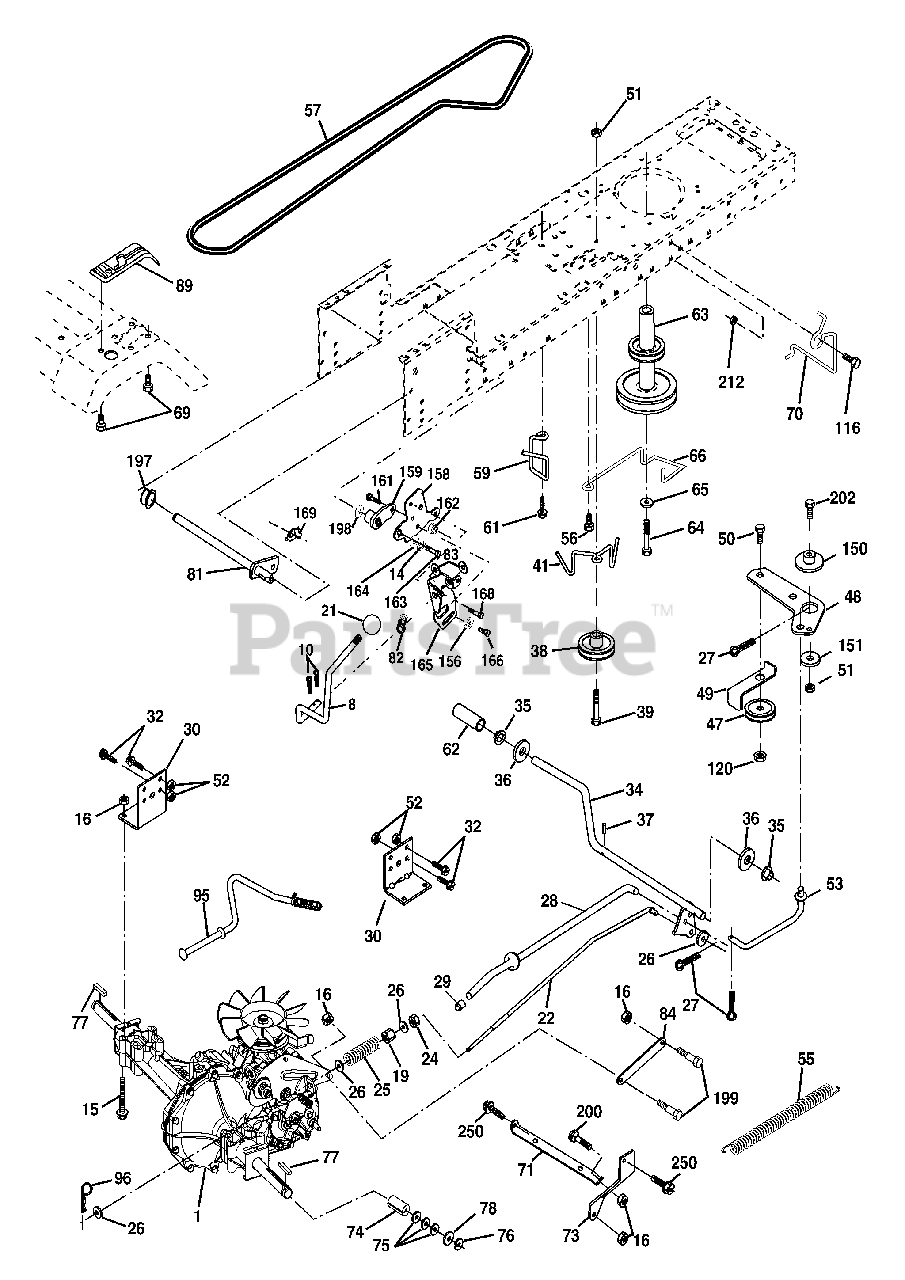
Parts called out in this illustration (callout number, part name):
10	Pin, Cotter 1/8 x 1
14	Washer Lock 1/4
15	Bolt Hex Flghd 5/16-18 Gr. 5
16	Nut, Lock Hex w/Ins 5/16-18 Unc
19	Nut, Lock Hex w/Wsh 3/8-16 Unc
21	Knob
22	Rod, Brake
24	Nut
25	Spring, Rod, Brake
26	Washer 13/32 x 13/16 x 16 Ga.
27	Pin, Cotter 1/8 x 3/4
28	Rod, Parking Brake
29	Cap, Parking Brake
30	Bracket, Transmission
32	Bolt Hex 5/16-18 Unc x 3/4
34	Shaft, Foot Pedal
35	Bearing, Nylon
36	Washer
37	Pin, Roll
38	Pulley, Idler, Composite
39	Bolt
41	Keeper, Belt, Idler
47	Pulley, Idler, V-Belt
48	Bellcrank Clutch Grnd Drustl
49	Retainer, Belt
50	Bolt 3/8-16 x 1-1/2 Gr. 5
51	Nut
52	Nut Crownlock 5/16-28
53	Link, Clutch
55	Spring, Return, Clutch
56	Screw 3/8-16 x 1-1/4
57	V-Belt, Drive
59	Keeper, Belt, Center
61	Screw, 3/8-16 x .875
62	Cover, Pedal
63	Pulley, Engine
64	Bolt Hex 7/16-20 x 4 x Gr. 5-1.5
65	Washer
66	Keeper, Belt Engine Hydro
69	Screw Hex Wsh Hi-Lo 1/4-1/2 Unc
70	Guide, Belt, Mower Drive RH
71	Strap, Torque, Lh
73	Strap, Torque, Rh
74	Spacer, Axle
75	Washer 25/32 x 1-1/4 x 16 Ga.
76	Ring, E
77	Key, Square
78	Washer 25/32 x 1-5/8 x 16 Ga.
81	Shaft Asm Cross
82	Spring, Torsion
83	Washer 17/32 x 3/4 x 16 Ga.
84	Link Transaxle
89	Console, Shift
95	Control Asm Bypass Hydro
96	Spring, Retainer 1"
116	Bolt 3/8-16 x 1
120	Bolt Hex 3/8-16 x 1-1/2
150	Spacer Retainer
151	Washer 13/32 x 2 x 10
156	Washer 5/16 x 1.0 x 1.25
158	Bracket Shift Mount
159	Hub Shift
161	Bolt Rdhd Sqnk 1/4-20 x 3/4 Gr. 5
162	Nut Crownlock 1/4-20 Unc
163	Bolt Hex Fin 1/4-20 x 1
164	Washer 5/8 x .281 x 10 Ga.
165	Bracket Pivot Lever
166	Screw 5/16 x 1.0 x .125
168	Bolt Shoulder 5/16-18 x .561
169	Plate Fastening LT
197	Nyliner Snap-in 5/8" ID
198	Washer Nyl 7/8ID x .105"HYD
199	Bolt Shoulder 5/16-18 Unc
200	Bolt Rdhd Sqnk 5/16-18 Unc x 1
202	Bolt Car SH 3/8-16 x 1-1/2 Gr 5
212	Nut Hex Flange Lock
250	Screw 3/8-16 x .75
